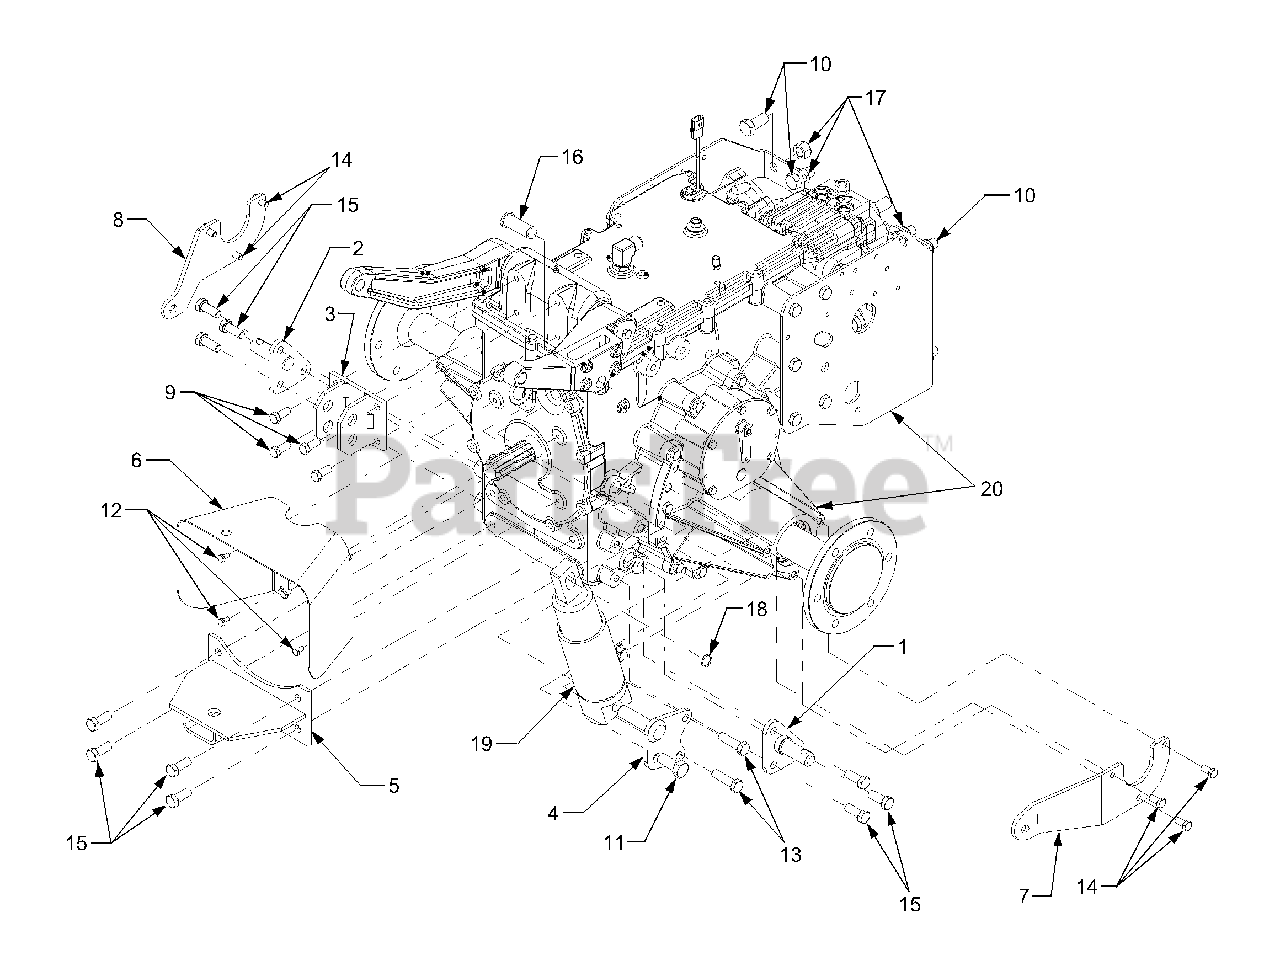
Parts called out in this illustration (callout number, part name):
1	Bracket, Lower Hitch RH
2	Bracket, Lower Hitch LH
3	Bracket, Top Link
4	Bracket, Cylinder
5	Bracket, Drawbar
6	Shield, PTO
7	Bracket, Chain LH
8	Bracket, Chain RH
9	Screw, Hex Cap 7/16-14 x 1/0 GR5
10	Screw, Hex Cap 5/8-18 x 1.31 GR5
11	Screw, Hex Cap 5/8-11 x 1.5 GR5
12	Screw, Hex Cap 5/16-18 x .5 GR5
13	Screw, Hex Cap 1/2-13 x 1.75 GR5
14	Screw, Hex Cap 3/8-16 x .75 GR5
15	Screw, Hex Cap 1/2-13 x 1.0 GR5
16	Pin, Lift, .75 x 2.125
17	Nut, Hex Lock, 5/8-18
18	Ring, Snap, 75 Dia
19	Cylinder, Lift
20	Transmission Assembly
